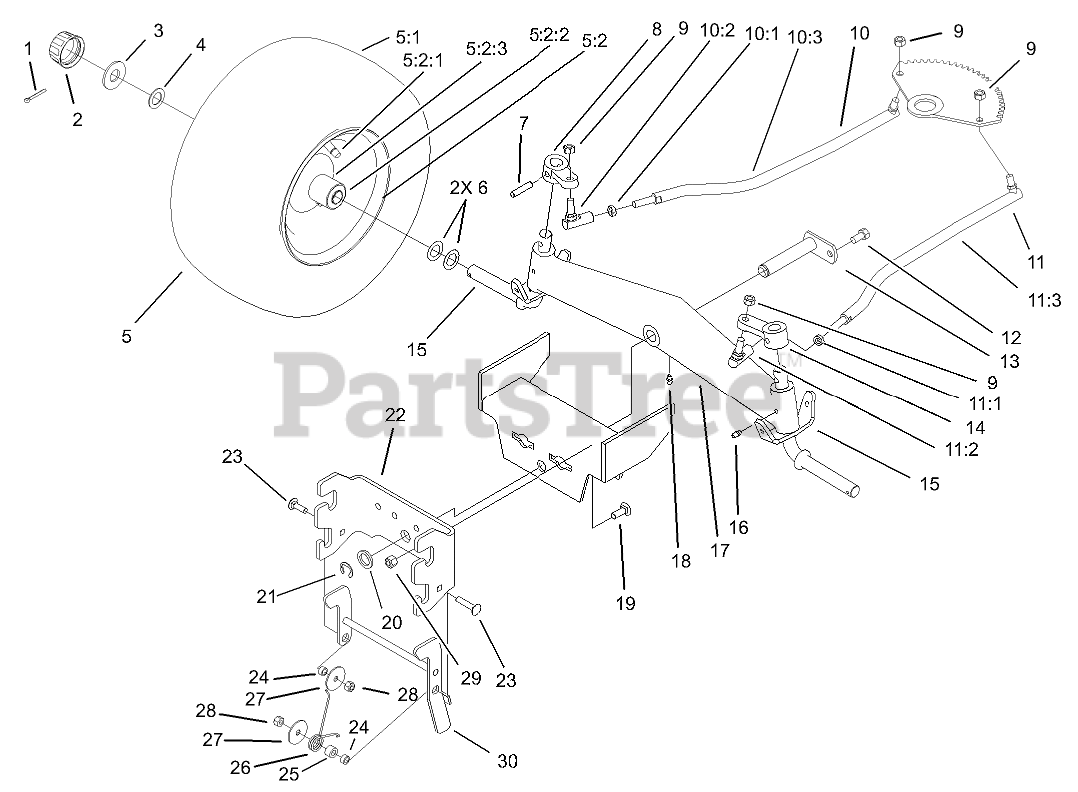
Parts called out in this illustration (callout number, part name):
1	PIN-COTTER
2	CAP-HUB
3	WASHER-PLAIN
4	WASHER
5	FRONT WHEEL & TIRE ASM
5:2	Wheel ASM
5:2:1	VALVE
5:2:2	BEARING-WHEEL
5:2:3	ZERK-GREASE
6	WASHER-SHIM
8	ARM-SPINDLE, LH
10	LINKAGE-STEERING, RH
10:1	NUT-JAM
10:2	BALL-JOINT
10:3	Ball Link ASM
11	LINKAGE-STEERING, LH
11:1	NUT-JAM
11:2	BALL-JOINT
11:3	Ball Link ASM
12	SCREW-HWH, TAPTITE
13	PIN-AXLE
14	ARM-SPINDLE, RH
15	SPINDLE
16	FITTING-GREASE
17	AXLE-FRONT
18	FITTING-LUBE, 45 DEG
19	BOLT-CARR
20	Washer
21	E-RING
22	HITCH-FRONT
23	BOLT-CARR
24	SPACER-YOKE, RIGHT
25	SPACER
26	SPRING-TORSION
27	WASHER-FLAT
28	NUT-LOCK, NI
29	NUT-LOCK, NI
30	LATCH ASM
